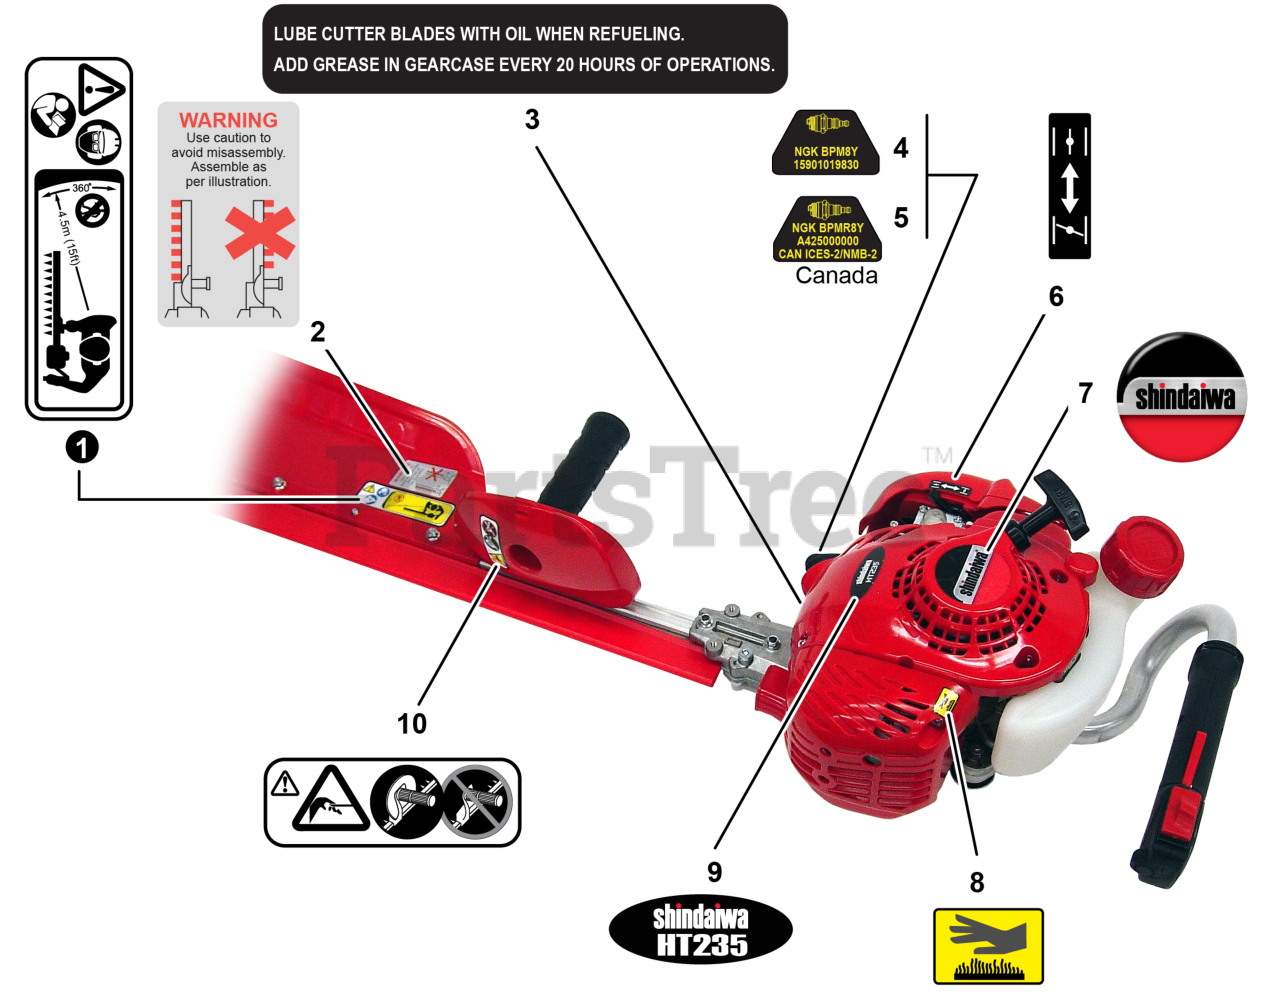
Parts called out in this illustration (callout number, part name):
1	LABEL - CAUTION
2	LABEL - WARNING
3	LABEL - LUBE BLADES
4	LABEL - SPARK PLUG - BPM8Y
5	LABEL - SPARK PLUG - BPMR8Y
6	LABEL - CHOKE
7	LABEL - SHINDAIWA
8	LABEL - CAUTION - HOT
9	LABEL - MODEL HT235
10	LABEL - CAUTION - ISO
